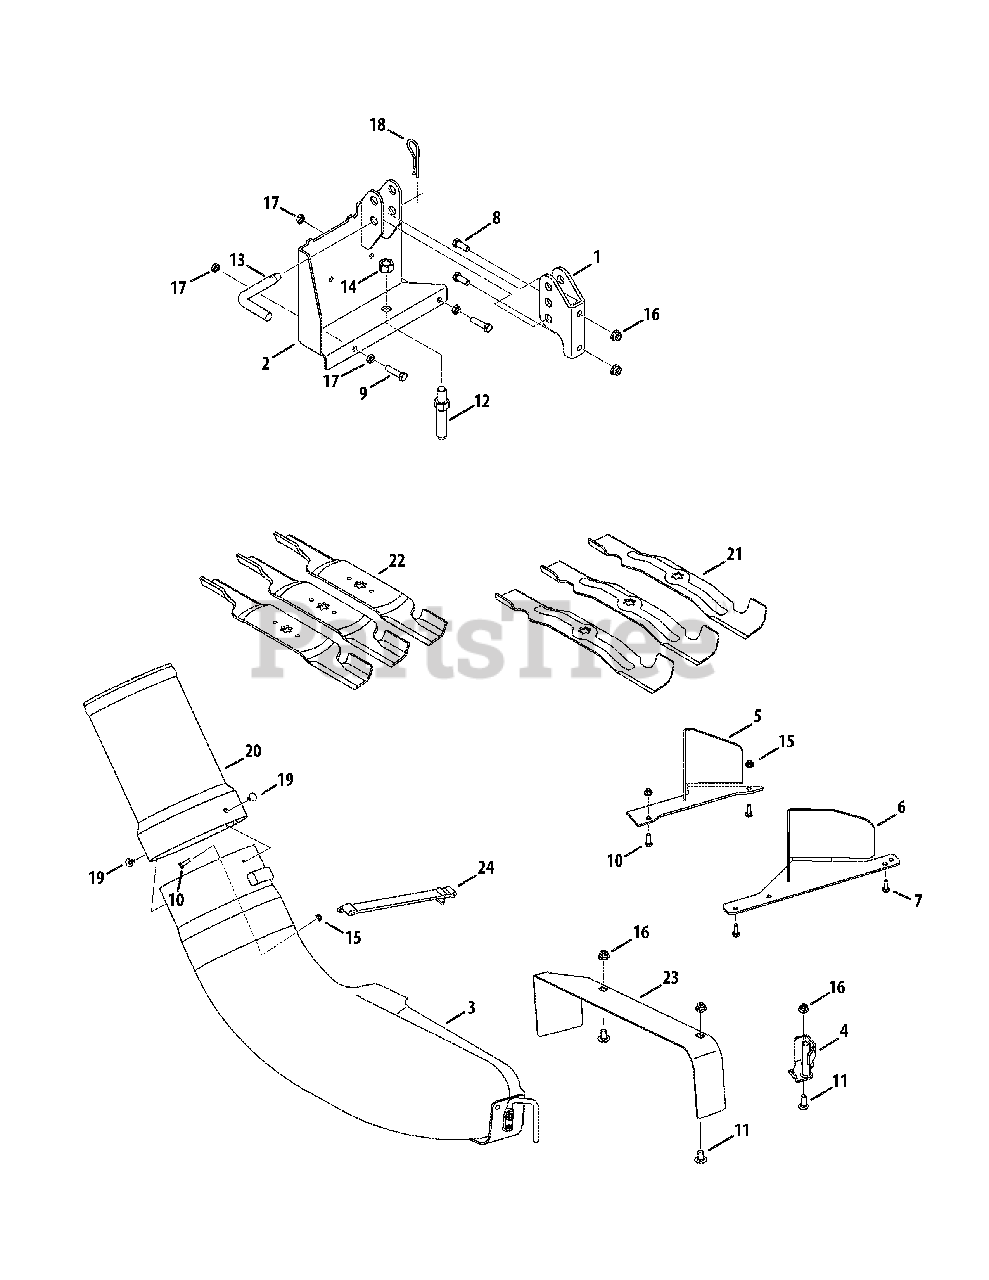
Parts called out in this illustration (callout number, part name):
1	Hitch Bracket
2	Bagger Mounting Assembly
3	Discharge Chute Assembly, 50" & 54"
4	Chute Stop Bracket
5	Deck Baffle, 50" Deck
6	Deck Baffle, 54" Deck
7	Self-tapp Screw, 5/16-18 x .750
8	Hex Head Screw, 3/8-16 x 1.00
9	Hex Head Screw, 3/8-16 x 1.50
10	Hex Head Screw, 1/4-20 x .75
11	Carriage Bolt, 3/8-16 x 1.00
12	Catcher Adapter Stud
13	Clevis Pin, R-Angle
14	Hex Nut, 5/8-18
15	Flange Lock Nut, 1/4-20
16	Flange Lock Nut, 3/8-16
17	Jam Nut, 3/8-16
18	Internal Cotter Pin, .148 x 3.00
19	Ratchet Clip
20	Bagger Chute Adapter
21	Blades, 17.90 Star
22	Blades, 18.50 Extra Hi-Lift
23	Chute Discharge Plate
24	Chute Strap
